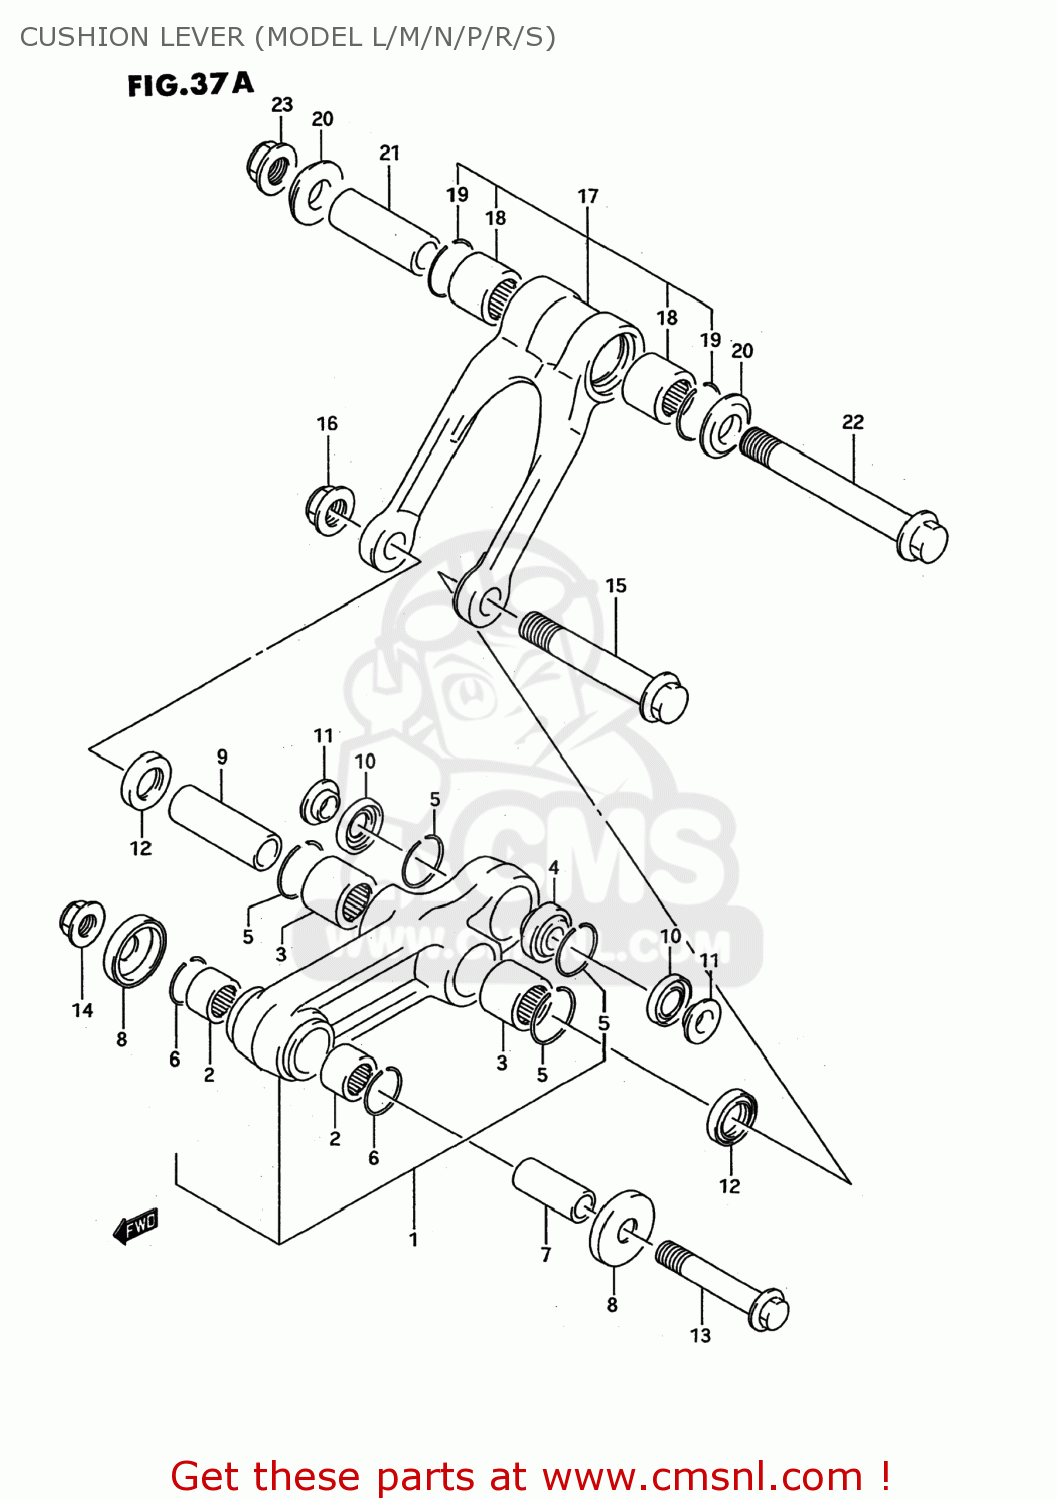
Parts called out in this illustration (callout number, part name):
1	LEVER SET,RR CUSHION
2	BEARING(14X20X12)
3	BEARING(17X24X20)
4	BEARING,RR CUSHION LEVER
5	RING,STOPPER
6	CIRCLIP,PISTON PIN
7	SPACER,RR CUSHION LEVER FR
8	SEAL,REAR CUSHION LEVER
9	SPACER,RR CUSHION LEVER CTR
10	SEAL,RR CUSHION LEVER RR DUST
11	SPACER,RR CUSHION LEVER RR
12	SEAL,OIL(17X24X3)
13	BOLT,RR CUSHION LEVER FR
14	NUT
15	BOLT,RR CUSHION LEVER CTR
16	NUT 12MM
17	ROD SET,REAR CUSHION,LEFT
18	BEARING(17X24X20)
19	RING,STOPPER
20	SPACER,RR CUSHION ROD SIDE
21	SPACER,RR CUSHION ROD
22	BOLT,RR CUSHION ROD
23	NUT 12MM
